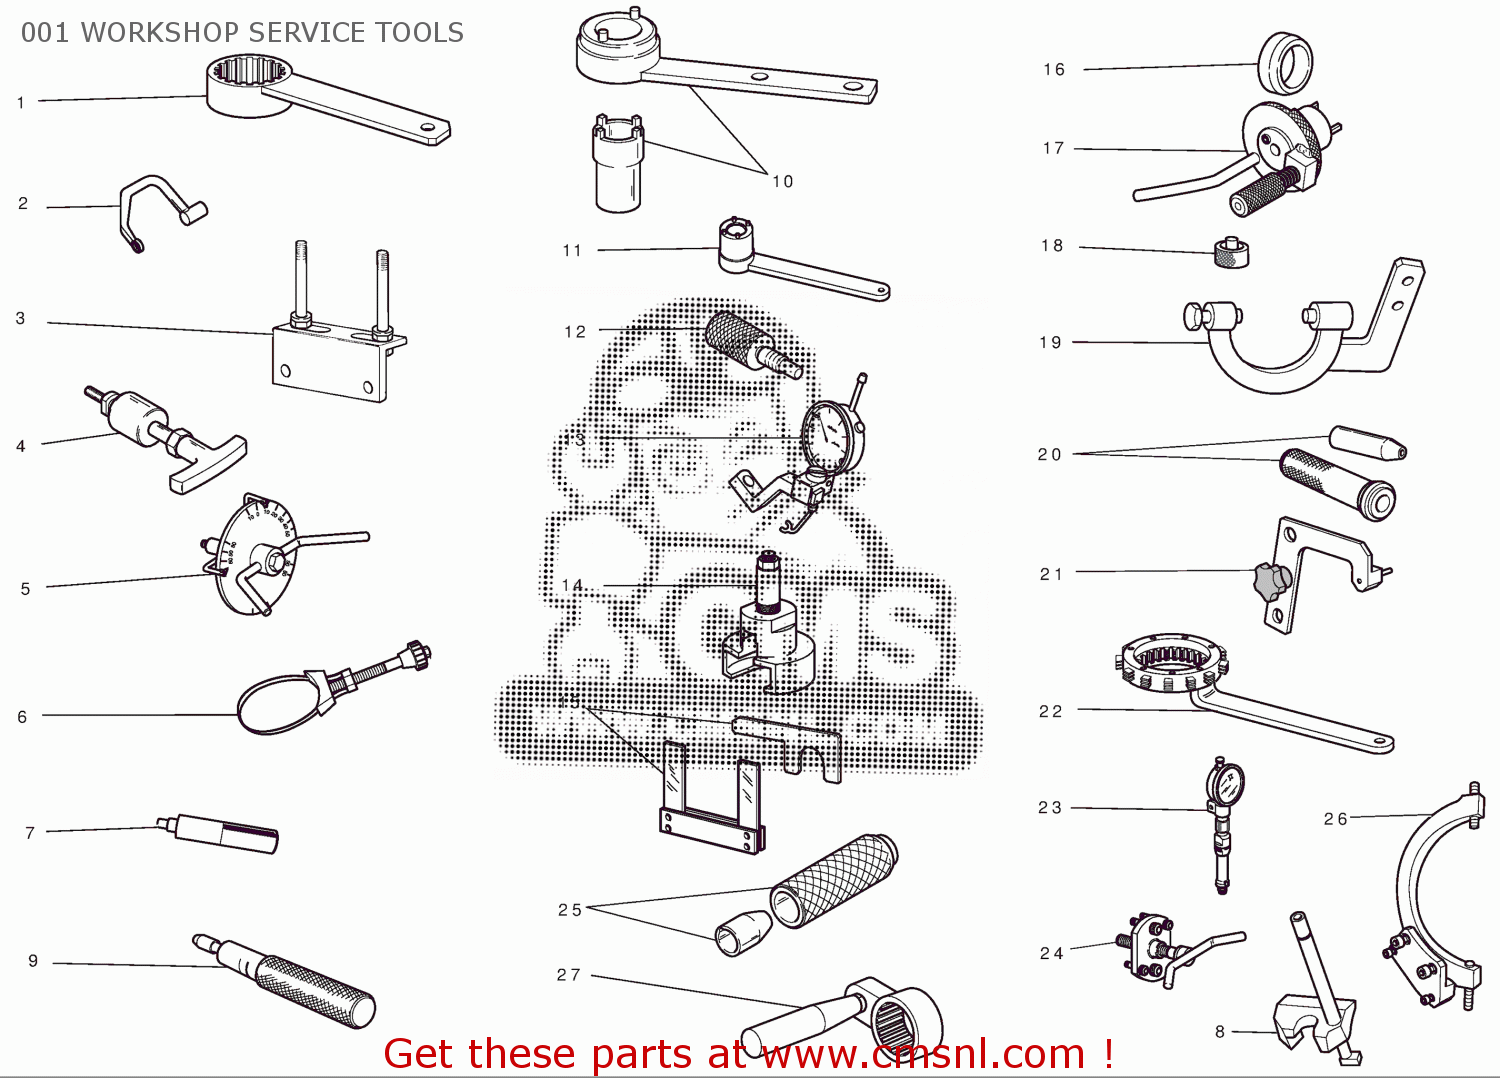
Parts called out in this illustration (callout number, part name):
1	Wrench for holding timing belt rollers ring nuts
2	HEAD NUTS HOLDER WRENCH
3	HEAD MOUNTING BASE
4	ROCKER PIN EXTRACTOR
5	TOOL ADVANCE CHECKING WITH DISC
6	WRENCH, OIL FILTER CARTRIDGE
7	TOOL ROLLER CAGE FITTING
8	CLOSING ROCKER & SPRING ASSEMBLING TOOL
9	TOOL, OIL SEAL MOUNTING
10	DRIVING ROLLER TIGHTENING TOOL
11	CRANKSHAFT GEAR RETAINING WRENCH
12	BELT ROLLER TIMING OF TWO-VALVE HEAD
13	VALVE LIFT GAUGE
14	EXTRACTOR FOR PRIMARY DRIVE GEAR
15	SPACER AND FORK FEELER GAUGE 0.2/0.3 MM
16	SLEEVE FOR INSTALLING CLUTCHBELL GEAR
17	CRANKSHAFT RESET TOOL
18	SPACER FOR CHECKING LOWER VALVE SHIM
19	FLYWHEEL WRENCH
20	CRANKCASES ASSEMBLING CAP
21	PLATE POSITIONING GEAR ENGAGEMENT FORK
22	WRENCH HOLD CLUCH HOUSING DRUM STEADY
23	T.D.C. CONTROL GAUGE
24	DRIVE ROLLER PULLER
25	SNAP RINGINSTALLATION TOOL
26	FLYWHEEL WRENCH
27	WRENCH FOR HOLDING TIMING BELT ROLLERS
